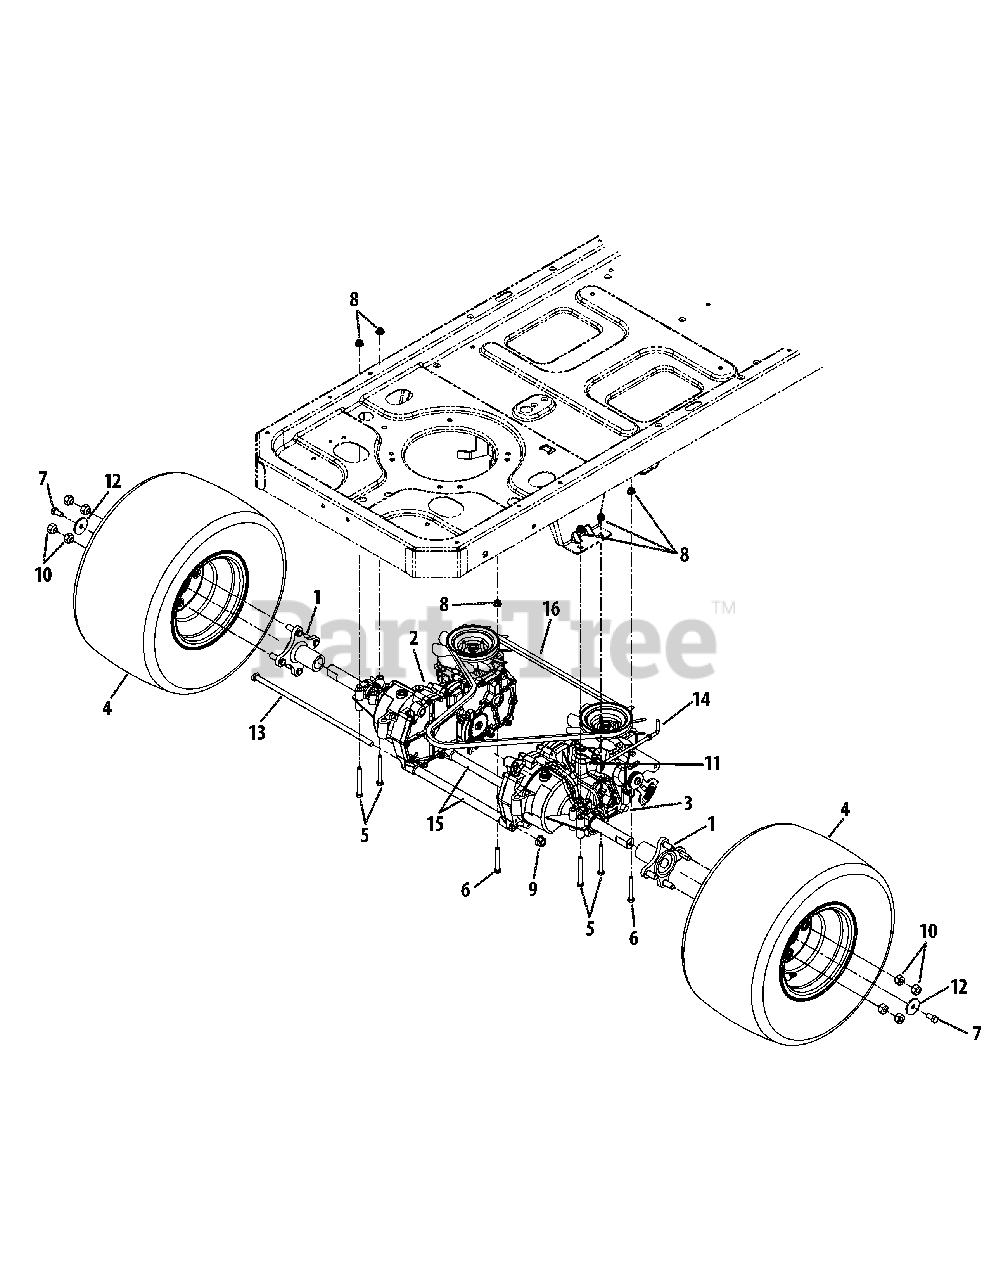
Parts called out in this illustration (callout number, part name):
1	Wheel Hub
2	Transmission Assembly, LH
3	Transmission Assembly, RH
4	Wheel Assembly, 18 x 9.5 x 8
5	Hex Screw, 5/16-18 x 2.75
6	Hex Screw, 5/16-18 x 2.25
7	Hex Lock Screw, 3/8-16 x .75
8	Hex Flange Lock Nut, 5/16-18
9	Hex Flange Lock Nut, 7/16-20
10	Lug Nut, 7/16-14
11	Bow-Tie Cotter Pin
12	Flat Washer, .39 x 1.5 x .134
13	Rod, .405 x 14.0
15	Tube, .45 x .69 x 10.2
16	V-Belt
